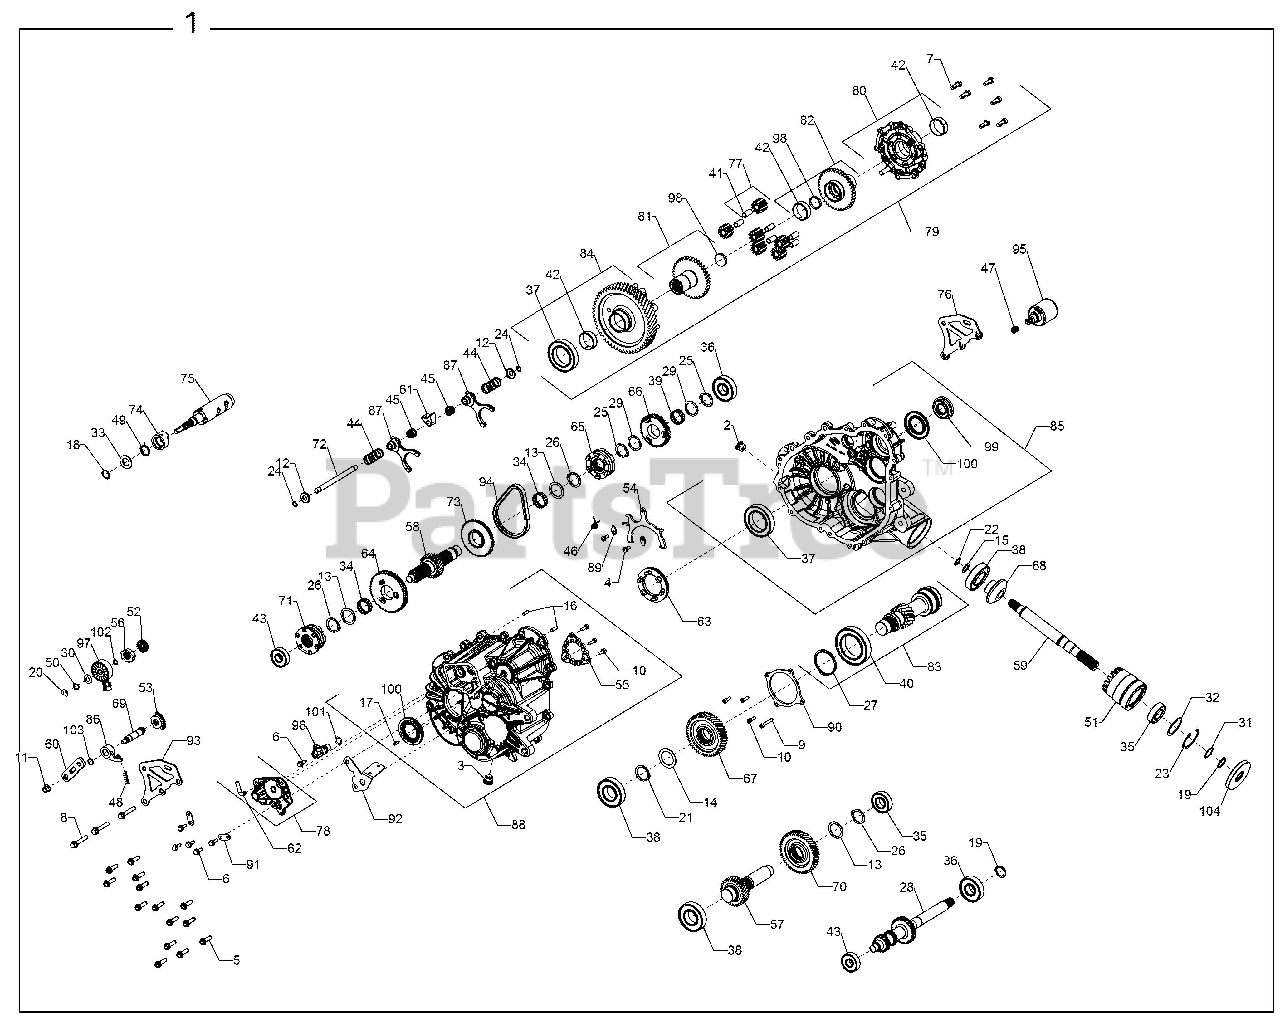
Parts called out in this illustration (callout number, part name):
1	ASM., MAIN GEARCASE
2	PLUG-SKT HD 1SO 6149,M18 X 1.5
3	PLUG-SOCKET HEAD W/MAG,M18X1.5
4	SCREW, TORX PAN HD M6 X 1 X 16
5	SCREW-HEXFLANGEHEAD,M8X1.25X30
7	SCREW-CAP HH,M8 X 1.25 X 20
9	SCR-M6X1.0X40,SOC/CAP(105344)
10	SCR-SCKT HD,CP,M6X1X18(105355)
11	NUT-M8X1.25,HXFLG,NYLN(110093)
12	WASHER-CUP
16	PIN, DOWEL, 6 X 20
17	SPRING-SLOTTED PIN,6MM
18	RING, RETAINING BASIC EXTERNAL 0.75
19	RING, SNAP
20	RING-RETAINING
21	RING,RETAINING
22	RING,RETAINING,EXTERNAL SHR-66
23	RING,RETAININGBASICINTRNL2.047
24	RING-RETAINING
25	RING,RETAINING
26	RING, RETAINING, EXTERNAL
27	RING, RETAINING
28	SHAFT-PINNION,INPUT,BOSS,LW
29	WASHER,THRUST
30	WASHER,THRUST,.446X.88X.025
31	SHIM 1.180 X .995
32	SHIM 2.040 OD X 1.630 ID
33	SPACER, 19.4 X 34 X 2
34	BEARING,NEEDLE
37	BEARING, BALL
38	BEARING-BALL
39	BEARING,NEEDLE
40	BEARING, BALL
41	BEARING,PLAIN,10X12X25
42	PLAIN,BEARING 40X44X15
43	BEARING, BALL
44	SPRING-COMPRESSION
45	SPRING-COMPRESSION
46	SPRING, TORSION RETURN
47	SPRING,COMPRSSN.54ODX.44IDX.05
48	SPRING, COMPRESSION DETENT
49	SPRING, TORSION
50	WASHER-SPRING,210393
51	TUBE, SNORKLE MACH
52	GEAR-SECTOR,16T
53	GEAR-SECTOR,31T-CUT TO 11T
54	SHIFT FORK (270507)
55	PARK PLATE (270509)
56	STAR, DETENT
57	SHAFT, IDLER, 29T
58	SHAFT,REVERSE,25T (285878)
59	SHAFT-FRONT OUTPUT(285914)
60	BELLCRANK
61	COLLAR-SHIFT
62	TUBE-VENT,90-1/4" HOSE
63	DOG-ENGAGEMENT
64	GEAR-LOW,67T(352856)
65	DOG, ENGAGEMENT, 6-FACE
66	GEAR, 53T
67	GEAR, 46T, STAGE 3
68	GEAR-13T,FRONT OUTPUT(352957)
69	SHAFT, SHIFT
70	GEAR,48T STAGE 2 (353115)
71	SHIFT DOG, PARK/LOW (353357)
72	RAIL-SHIFT SHAFT(353622)
73	SPROCKET, 48T, 6-FACE
74	PARK CAM
75	DRUM, SHIFT MACH
76	WELD-REAR MOUNT BRKT
77	GEAR SUBASSEMBLY
78	SUBASSY COVER, SECTOR GEARS
79	DIFF-LOCKING (411600)
80	SUBASSY-COVER,DIFF (411601)
81	SUBASSY-GEAR,39T SIDE (411607)
82	SUBASSY-GEAR,39T SIDE (411608)
83	ASM-SUB,PINION SHAFT(411759)
84	SUBASSY-GEAR,53T (411797)
85	SUBASSY,LH CASE(411919)
86	ROLLER PAWL
87	SUBASSEMBLY, SHIFT FORK
88	SUBASSEMBLY RH COVER
89	RETAINER-FORK
90	COVER, BEARING, CENTER DRIVE
91	BRKT-MOUNT(430592)
92	BRKT-MNT,HARNESS
93	BRKT-REAR MOUNT
94	CHAIN, SILENT
95	SOLENOID
96	SENSOR-SPEED,TRANS
97	SWITCH, ROTARY 2 PIN RESISTIVE
98	PLUG,EXPANSION,1 1/4
100	SEAL-TRIPLE LIP,VITON,40X70X7
101	O-RING, -113
104	SEAL-TRIPLE LIP 25X80X10
